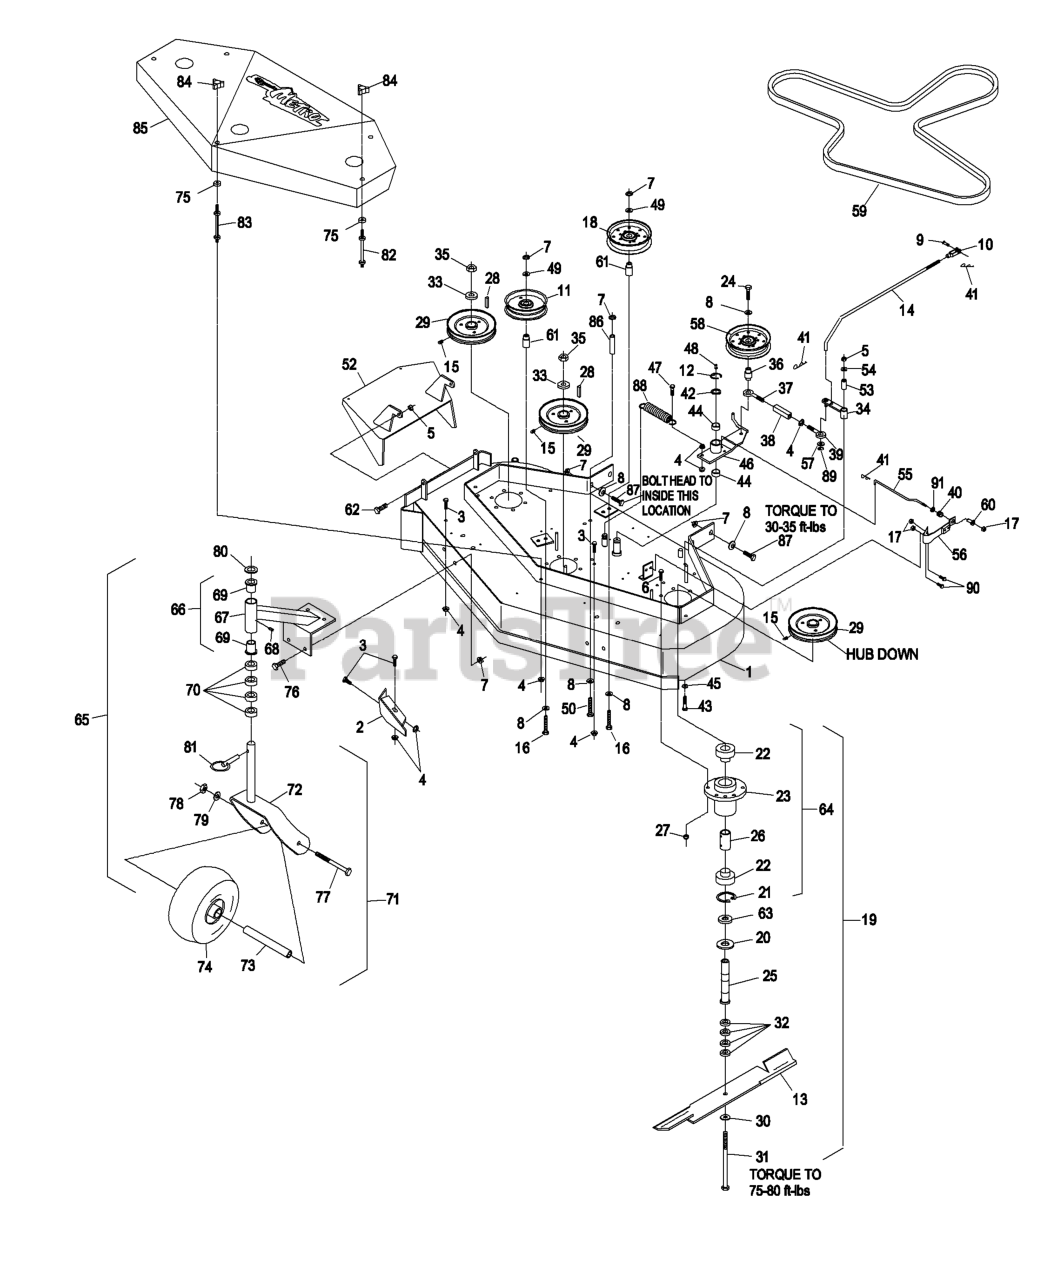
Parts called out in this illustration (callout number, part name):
1	DECK-SERVICE, 48
2	BAFFLE-DOGLEG
3	SCREW-HH
5	NUT-LOCK, NI
6	SCREW-HH
7	NUT-HHF, WHIZ
8	WASHER-BELLEVILLE
9	PIN-CLEVIS
10	YOKE-ADJUSTABLE
11	PULLEY-IDLER
12	RING-RETAINING, EXT
14	ARM-ASSIST, LINKAGE
15	SCREW-SET
16	SCREW-HH
17	NUT-LOCK, NI
19	HOUSING,CUTTER COMPLETE(S
20	GUARD-BEARING, BOTTOM
21	RING-SNAP
22	BEARING
24	SCREW-HH
25	TUBE-SPINDLE, SHORT
26	SPACER-BEARING
27	NUT-LOCK, NI
29	SHEAVE
30	WASHER-SPRING
31	SCREW-CAP, HH
33	WASHER-RETAINER, SHEAVE
34	ARM-ASSIST
35	NUT-HEX
36	BUSHING-ENGAGEMENT
37	EYEBOLT-THREAD, LH
38	BODY-TURNBUCKLE
39	EYEBOLT-THREAD, RH
40	SPRING-COMPRESSION
41	PIN-COTTER
42	WASHER-SPINDLE
43	SCREW-HH
44	SLEEVE-BEARING
45	WASHER-SPRING
46	ENGAGE ARM ASM
47	SCREW-HH
48	FITTING-GREASE
49	WASHER-FLAT
50	SCREW-HH
51	NUT-LOCK, NI
52	WLD,CHUTE 48
53	TUBE-PIVOT
54	WASHER-FLAT
55	ROD-BRAKE
56	PAD AND SPRING ASM
57	WASHER-PLAIN
59	BELT,BLADE 48
60	SPACER-FLANGED
62	SCREW-HH
63	SPACER-PULLEY/BEARING
65	CASTER/MOUNT ASM
66	SUPPORT ASM
68	FITTING-GREASE
69	BEARING-FLANGED
70	SPACER-CASTER
76	SCREW-HH
77	SCREW-HH
78	NUT-HH
79	WASHER-LOCK
80	WASHER-FLAT
82	STUD-SHIELD, BELT (SHORT)
83	STUD-SHIELD, BELT (LONG)
84	KNOB-3 PRONG
87	SCREW-HH
88	SPRING-EXTENSION
89	RING-RETAINING, EXT
90	SCREW-HH
91	RING-PUSH ON
